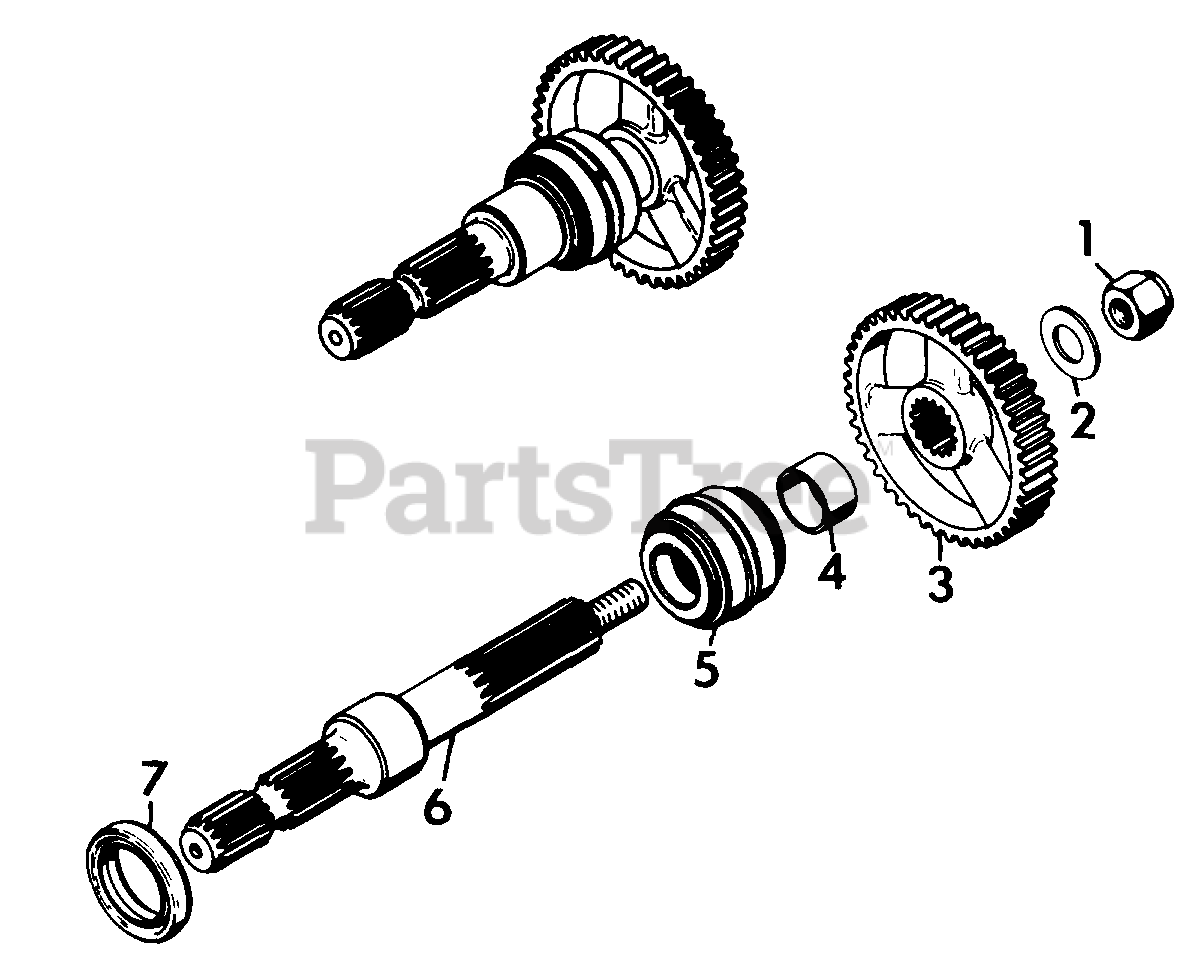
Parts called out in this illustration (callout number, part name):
1	NUT, LOCK 5/8-11
2	WASHER, FLAT .687X1.312X.122
3	GEAR, SPUR PTO; 10 DP 56 TEETH X .750 STD.
4	SPACER, 1.060X1.375X.450
5	ASSEMBLY, BEARING 1.000X1.980X1.243
6	SHAFT, PTO
7	SEAL, OIL 1.375X2.129X.312
